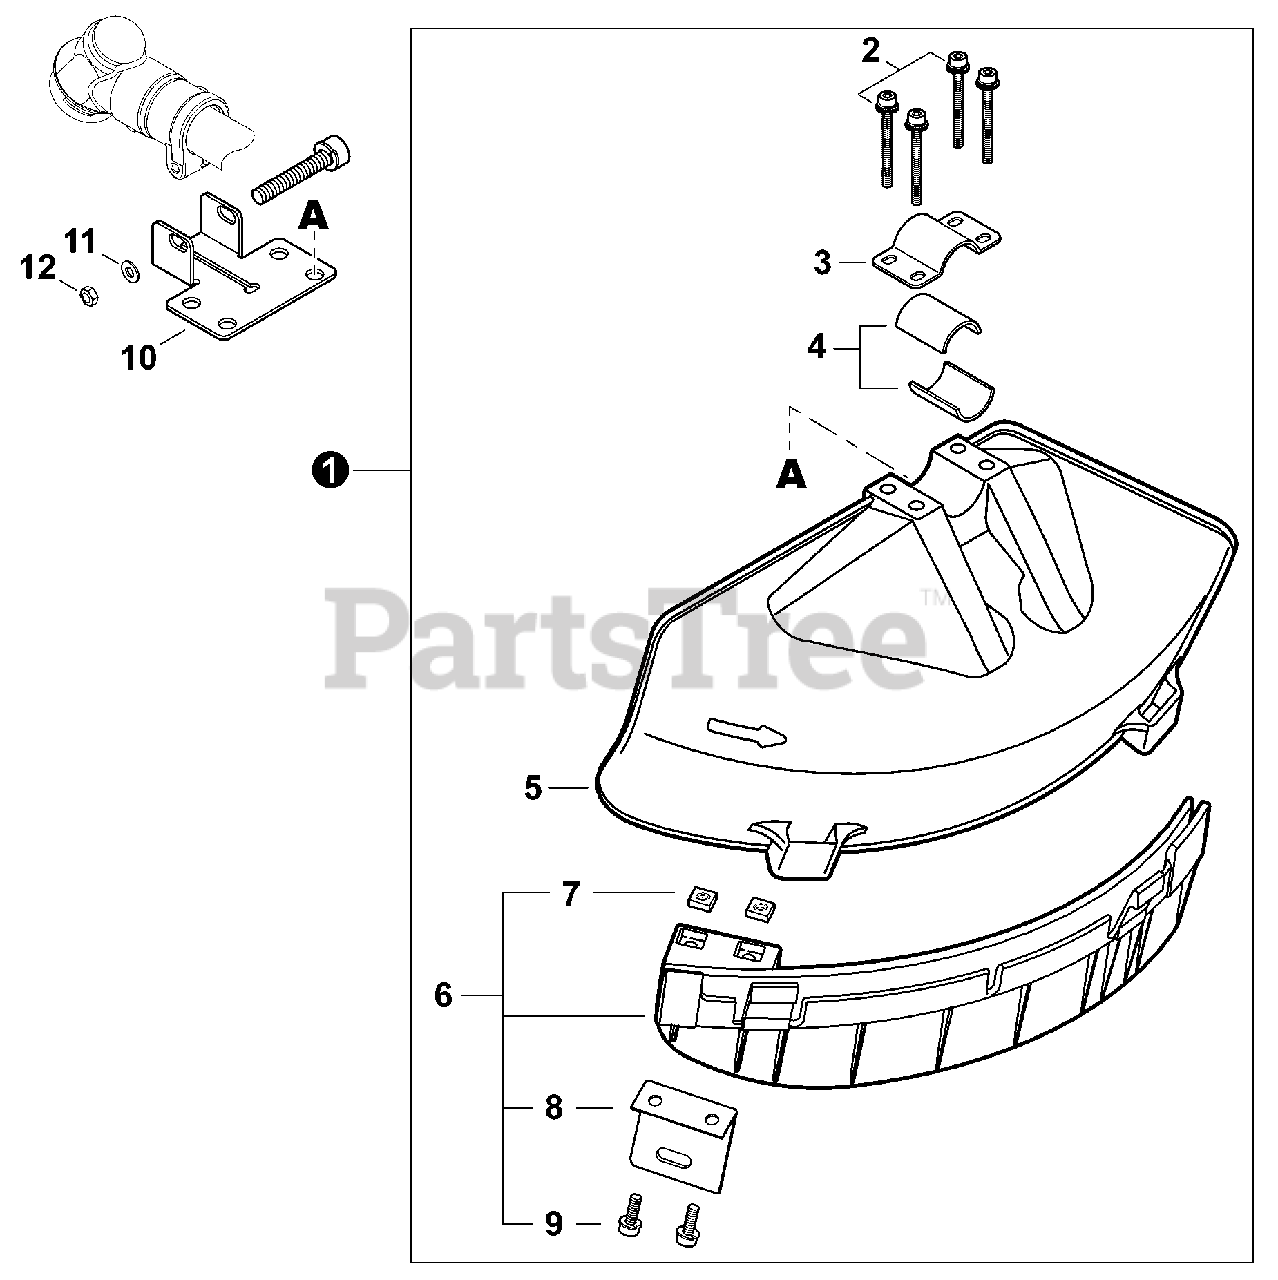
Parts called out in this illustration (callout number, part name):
1	DEBRIS SHIELD KIT
2	BOLT M5×45
3	CLAMP, UPPER
4	SPACER 26
5	SHIELD, DEBRIS PLASTIC
6	DEBRIS SHIELD EXTENSION ASSY
9	BOLT 5×16
10	PLATE, SHIELD MOUNTING
11	WASHER 6.5×13×1
12	NUT, HEX M6
